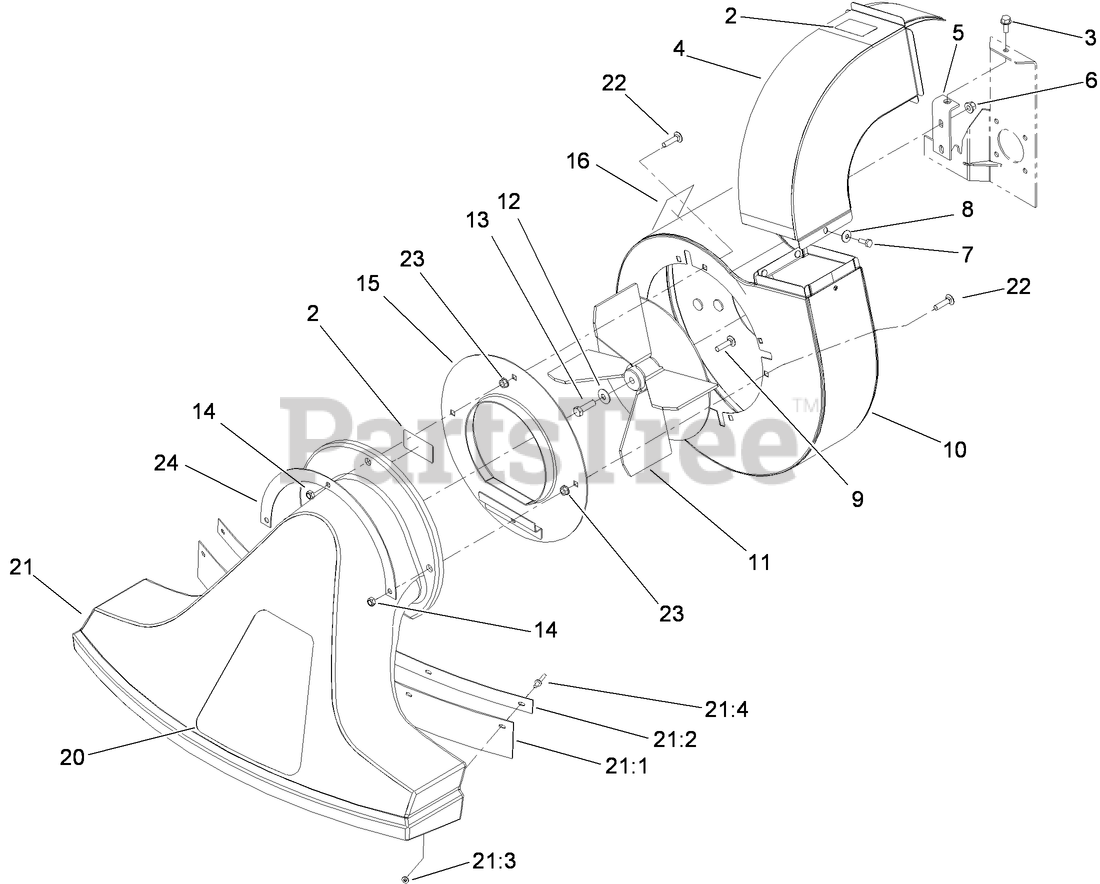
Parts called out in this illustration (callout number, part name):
2	DECAL-CAUTION, BAG
3	SCREW-HWHTF
4	VACUUM CHUTE ASM
5	BRACKET-MOUNTING, HOUSING
6	NUT-HF, NI
7	SCREW-HH
8	WASHER-BELLEVILLE
9	BOLT-CARR
10	BLOWER/VAC HOUSING ASM
11	FAN ASM
12	WASHER-BELLEVILLE
13	SCREW-HH
14	NUT-LOCK, NI
15	COVER-BLOWER
16	DECAL-WARNING, ROTATE
21	SNOUT ASM
21:1	FLAP-RUBBER
21:2	CLAMP-FLAP
21:3	WASHER-FLAT
21:4	RIVET-POP
22	SCREW-CARR
23	NUT-HF
24	FLANGE-RETAINER
